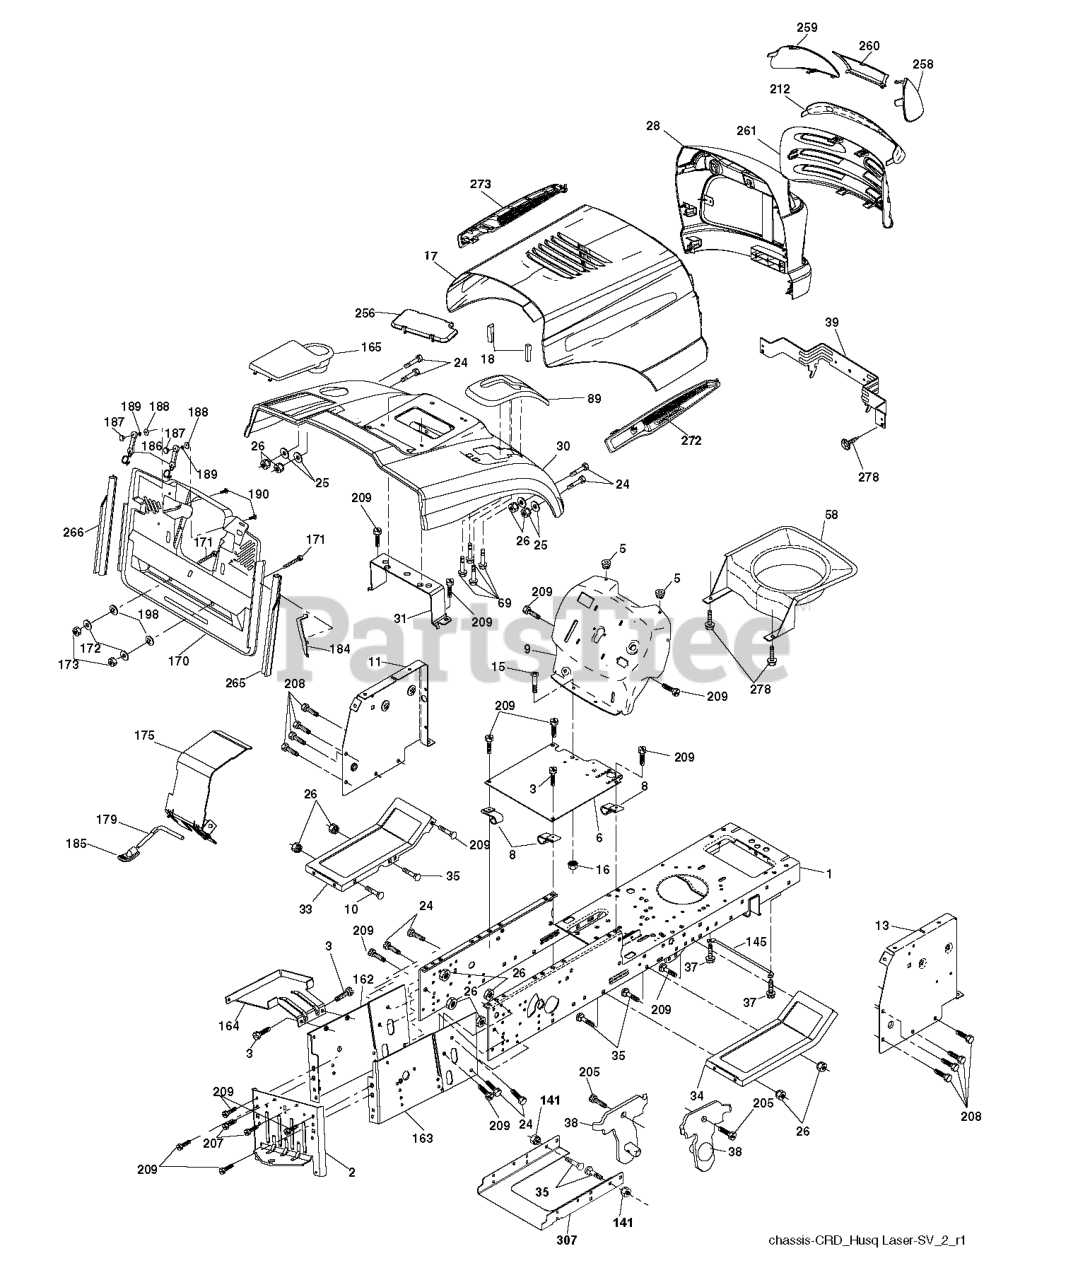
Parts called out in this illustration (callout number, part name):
2	DRAWBAR
3	SCREW 3/8-16X3/4
5	BUMPER.RUBBER.HOOD
6	PLATE
8	CLIP,INSULATOR
9	DASH.SLK.LT.PL.CC.NA.NHM.CE
10	BOLT D
11	PANEL.DASH.LH.LTX
13	PANEL ASM, DASH RH
15	Screw, Machine, Truss Head 5/16-18 UNC x 3/4
16	NUT
17	HOOD.PNT.LASER.SV.LT.668
18	BUMPER.HOOD.LARGE.1.75"
24	BOLT
25	WASHER
26	NUT
28	GRILLE.HUSQ.LASER.LT.668
30	FENDER.PNT.CRD.MS-668
31	BRACKET SUPPORT FENDER
33	FOOTREST.LH.BLACK
34	FOOTREST.RH.BLACK
35	BOLT
37	Screw 5/16-18 x 1/2 Hex, Self Tapping 5/16-18 x 1/2
38	BRACKET ASM PIVOT MOWER REAR
39	BRACKET PIVOT
69	SCREW.HI-LO.CONSOLE
89	CONSOLE.CRD.AUTO.BLACK.
141	NUT LOCK FLG 3/8-16 UNC
145	ROD.PIVOT.HOOD
162	BRACKET
163	BRACKET EXTEN CHASSIS RH CRD
165	COVER.BATTERY.CRD.BLACK
171	BOLT
172	WASHER
175	DOOR TRAP
179	ROD PIVOT FBI
184	BRACKET.ACTUATOR.BAGGER.SRD
185	KNOB.BRAKE.PARKING.ROD
186	LATCH ASSY
187	WELDNUT
189	LOCKWASHER #10
190	SCREW
205	SCREW LT
207	SCREW, 5/16-18 X 1/2
208	SCREW 3/8-16X1/2
209	SCREW, 3/8-16X3/4
212	INSERT.LENS.REFLECTIVE
256	COVER FENDER CRD
258	LENS LH
259	LENS LH
260	COVER.LENS.HUSQ.LASER.LT.498
261	INSERT.GRILLE.HUSQLASER.LT.498
265	SEALING
266	SEALING
272	VENT.HOOD.LASER.III.SD.RH
278	SCREW.#10 X 0.750.BOS
307	GUARD 107 CRD FRENCH GUARD HYD
